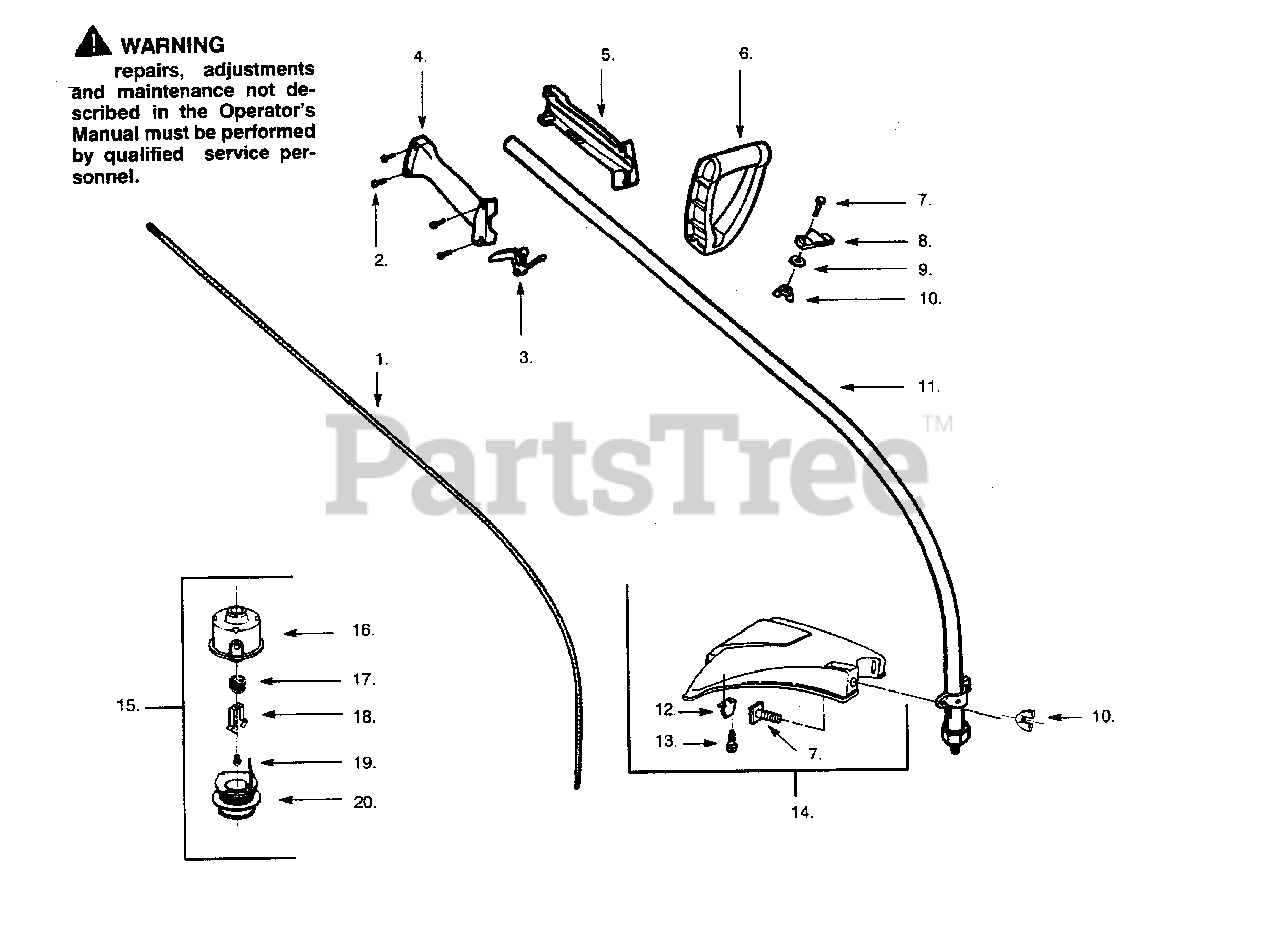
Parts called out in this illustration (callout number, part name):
1	Drive Shaft
2	Screw-Throttle Hsg.
4	Throttle Hsg. (Right)
5	Throttle Hsg. (Left)
6	Assist Handle
7	Bolt-Handle/Shield
8	Clamp-Handle
9	Washer-Handle
10	Wingnut-Handle/Shield
11	Drive Shaft Hsg. Ass'y
12	Line Limiter
13	Screw-Line Limiter
14	Shield Kit Ass'y. (Incl. 7, 10, 12 & 13)
15	Cutting Head Ass'y. (Incl. 16-20)
16	Hub Ass'y
18	Clip-Retainer-Head
19	Screw w/ Washer -Head
20	Spool w/Line
